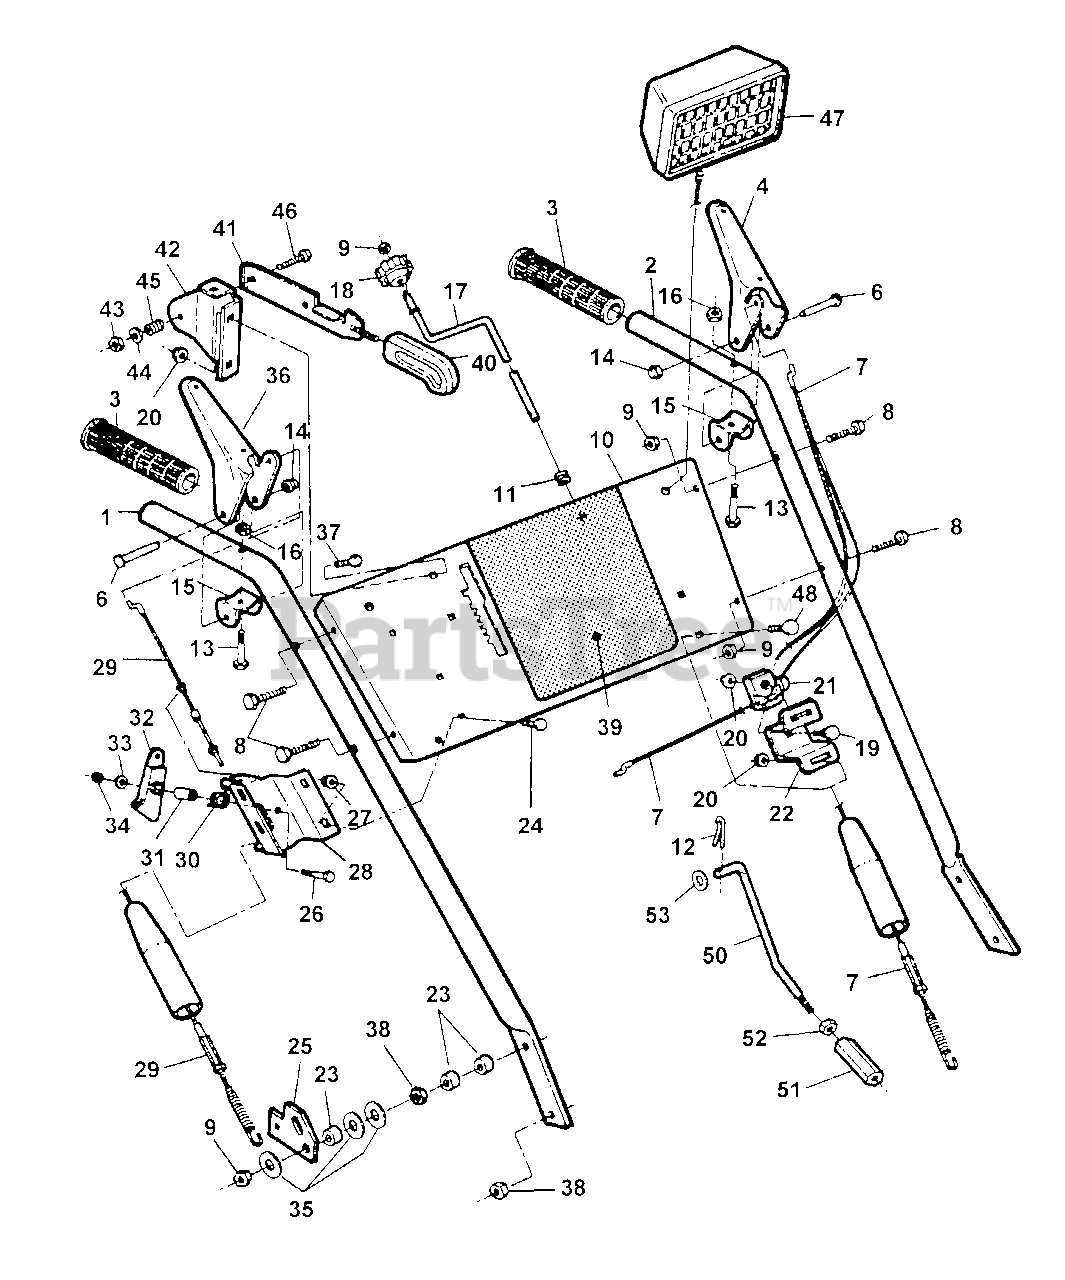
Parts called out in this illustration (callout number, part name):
1	BAR, Handle (Right Side)
2	BAR, Handle (Left Side)
3	GRIP, Handle
4	HANDLE, Left Side
6	PIN, 1/4 x 1-7/8" Clevis
7	CABLE, Left Side Clutch
8	SCREW, 5/16-18 x 1-1/2" Hex Head Cap, Grade 5
9	NUT, 5/16-18 Hex Center Lock, Grade B
10	PANEL, Control
11	BUSHING
12	PIN, 1/8 x 1" Cotter
13	SCREW, 1/4-28 x 1-3/8" Hex Head Cap, Grade 5
14	NUT, 1/4 Push
15	BRACKET, Handle
16	NUT, 1/4-28 Hex Top Lock
17	CRANK, Chute
18	KNOB, Chute Crank
19	BOLT, 1/4-20 x 3/4" Short Neck Carriage, Grade 5
20	NUT, 1/4-20 Hex Flange Lock
21	GUIDE, Cable
22	BRACKET, Cable Guide Support
23	SPACER, 5/16"
24	BOLT, #10-24 x 1/2" Flat Head Carriage
25	LEVER, Clutch
26	SCREW, 1/4-20 x 1" Hex Head Cap, Grade 5
27	NUT, #10-24 Hex Flange Lock
28	BRACKET, Cam
29	CABLE, Auger (Right Side)
30	SPRING Cam Lock
31	SPACER
32	LOCK, Cam
33	WASHER, 1/4 Flat
34	NUT, 1/4-20 Hex Center Lock, Grade B or 5
35	WASHER, 5/16 x 1-1/4" Flat
36	HANDLE, Right Side
37	BOLT, 1/4-20 x 1/2" Short Neck Carriage, Grade 5
38	NUT, 5/16-18 Hex Flange Lock, Grade 5
39	DECAL, Instruction
40	KNOB, Shift Handle
41	WELDMENT, Shift Handle
42	BRACKET, Shift Lever
43	NUT, 5/16-24 Hex Center Lock, Grade B
44	WASHER, 5/16" Flat
45	SPRING
46	SCREW, 5/16-24 x 1-3/4" Hex Head Cap, Grade 5
47	KIT, Light Assembly (Rectangular)
48	BOLT, 1/4-20 x 1/2" Short Neck Carriage, Grade 5
50	ROD, Upper Shift
51	NUT, 3/8-16 x 1-13/16 Connector
52	NUT, 3/8-16 Hex, Grade B
53	WASHER, 3/8" Flat
